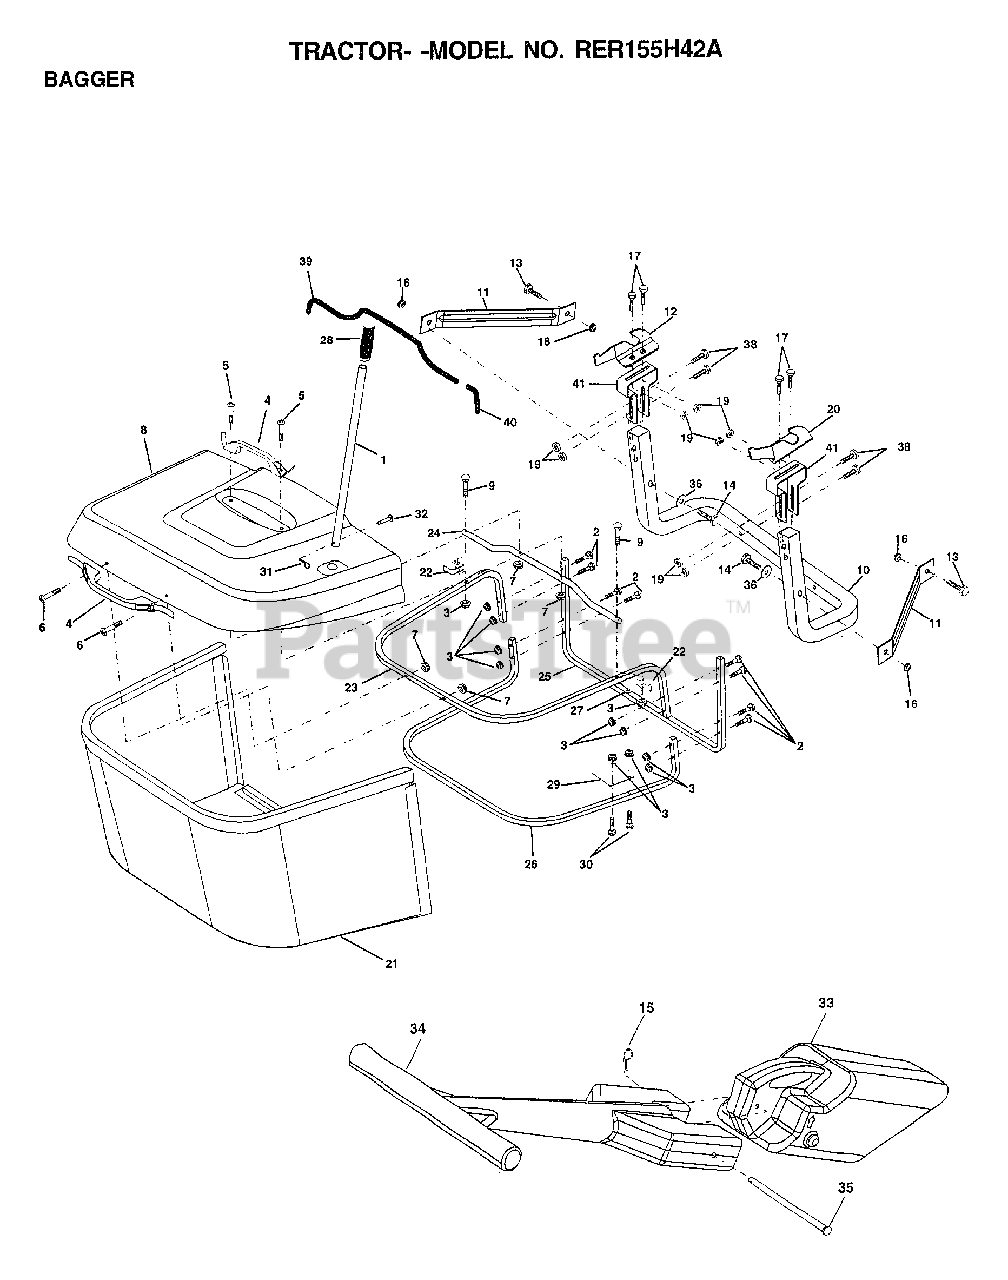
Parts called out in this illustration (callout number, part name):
1	TUBE.HDLE.BAG.CRD
2	BOLT.CARRIAGE.1/4-20X2.0
4	HANDLE BAGGER
5	"SCREW,PAN.HEAD"
7	NUT.WIZ.LOCK
9	BOLT CARRIAGE
10	TUBE SUPPORT BAGGER CRD
11	BRKT.SUPT.UPPER.BAG.CRD
12	BRACKET HORIZ ADJ BGGR LH CRD
13	BOLT
14	BOLT.HEX.3/8-16X2-1/2
17	BOLT
19	"NUT HEX,LOCK,FLAN"
20	BRACKET HORIZ ADJ BGGR RH CRD
21	BAG.ASM.CRD
22	BRKT.SIDE.BAG.CRD
23	TUBE.UPPER.BAG.CRD
24	TUBE.PIVOT.BAG.CRD
25	TUBE.FT.BAG.CRD
26	TUBE.LOWER.BAG.CRD.
27	BUSHING SNAP BAGGER CRD
28	GRIP.HANDLE.BLACK
29	PLATE.STOP.BAG.HDLE.CRD
30	BOLT.CARRIAGE
31	RETAINER M
32	RIVET.DRILL.1.75
33	PLUG MULCH
34	HANDLE.MULCHER.92.CRD
35	PIN.MULCHER.92 CRD
38	BOLT.5/16-18X2.5
41	BRACKET VERT ADJ BAGGER CRD
